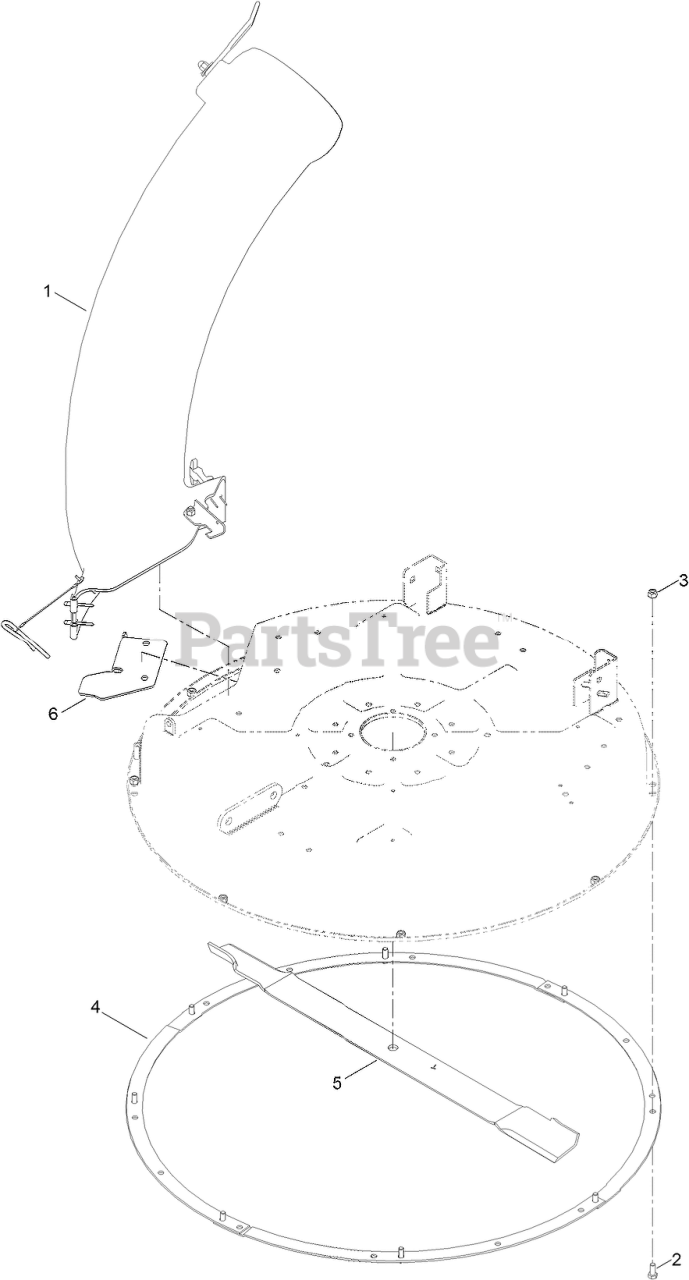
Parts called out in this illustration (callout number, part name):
1	CHUTE ASM-32"
2	SCREW-HH
3	NUT-HEX
4	RING-DECK
6	BRACKET-CUTOFF
